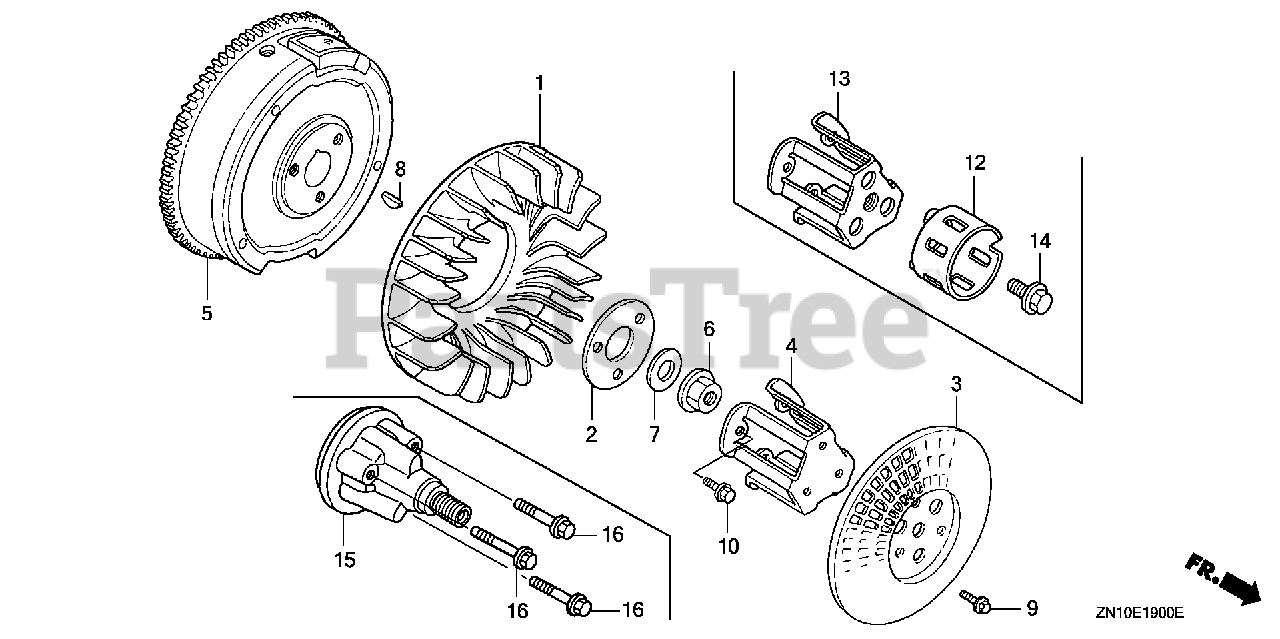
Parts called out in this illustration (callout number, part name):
1	FAN, COOLING
2	PLATE, COOLING FAN SETTING
5	FLYWHEEL
6	NUT, FLANGE (20MM)
7	WASHER (20MM)
8	KEY, SPECIAL WOODRUFF (25X18)
10	BOLT, FLANGE (8X16) Use from Engine SN 1000016.
